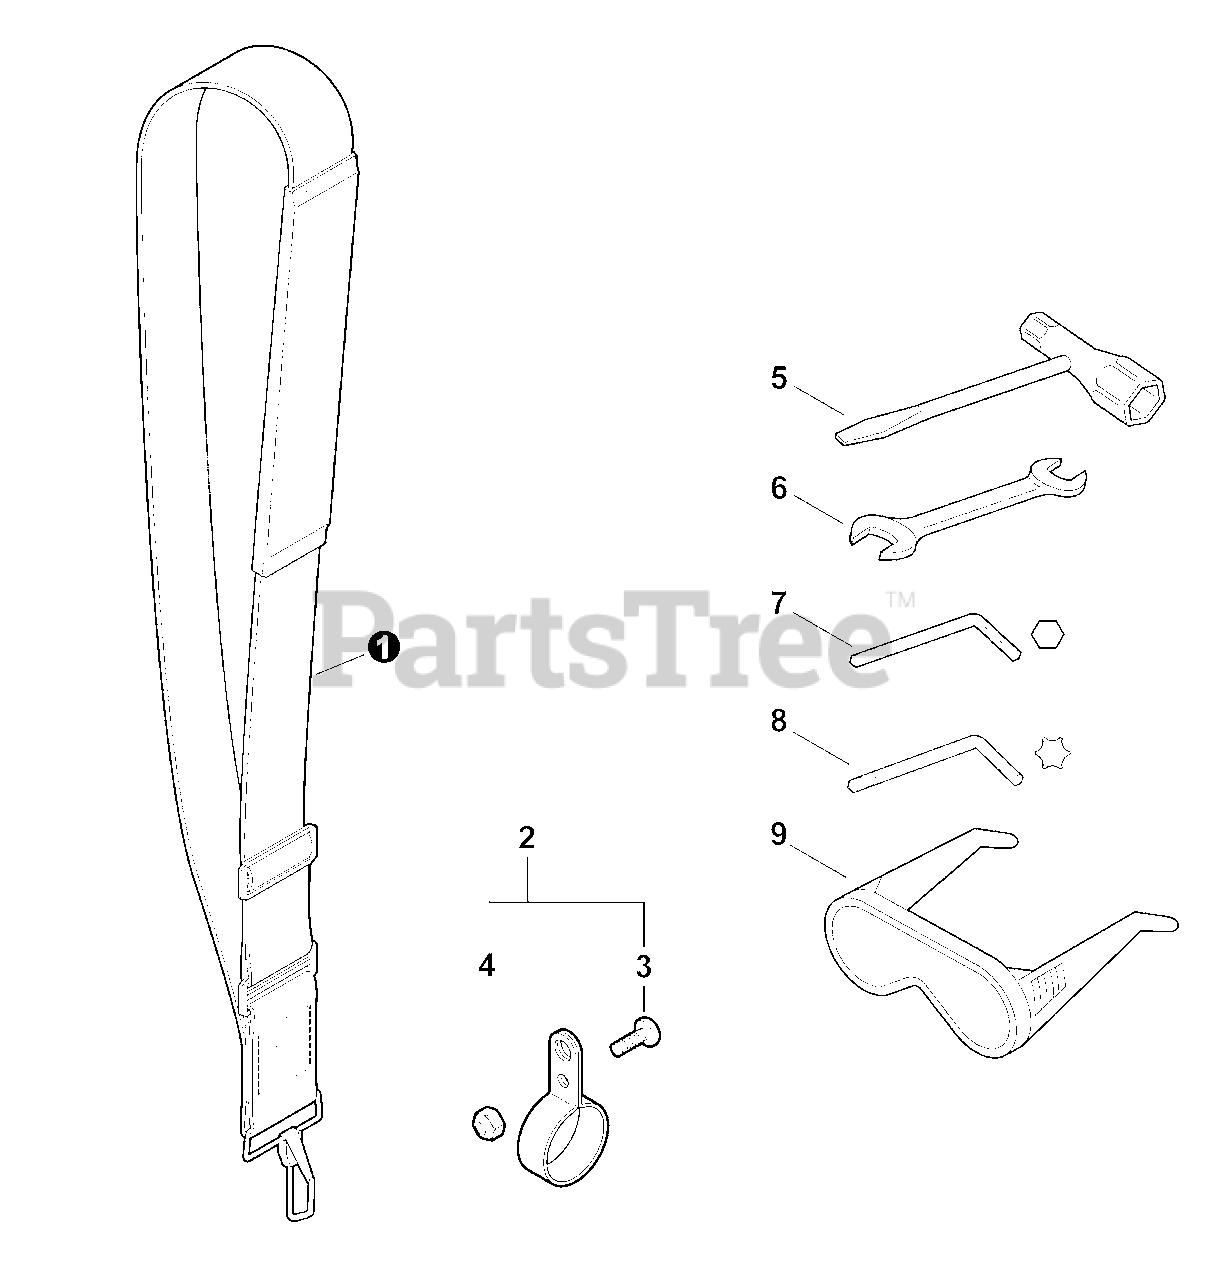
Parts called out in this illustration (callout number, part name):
1	STRAP ASSY, SHOULDER
2	HANGER KIT
3	BOLT, TORX 5×10
4	NUT, M5×8 NYLON INSERT
5	T-WRENCH 10×19 MM
6	SPANNER 8×10
7	WRENCH, ALLEN 4 MM
8	WRENCH, T27 80×30
9	GLASSES, SAFETY
